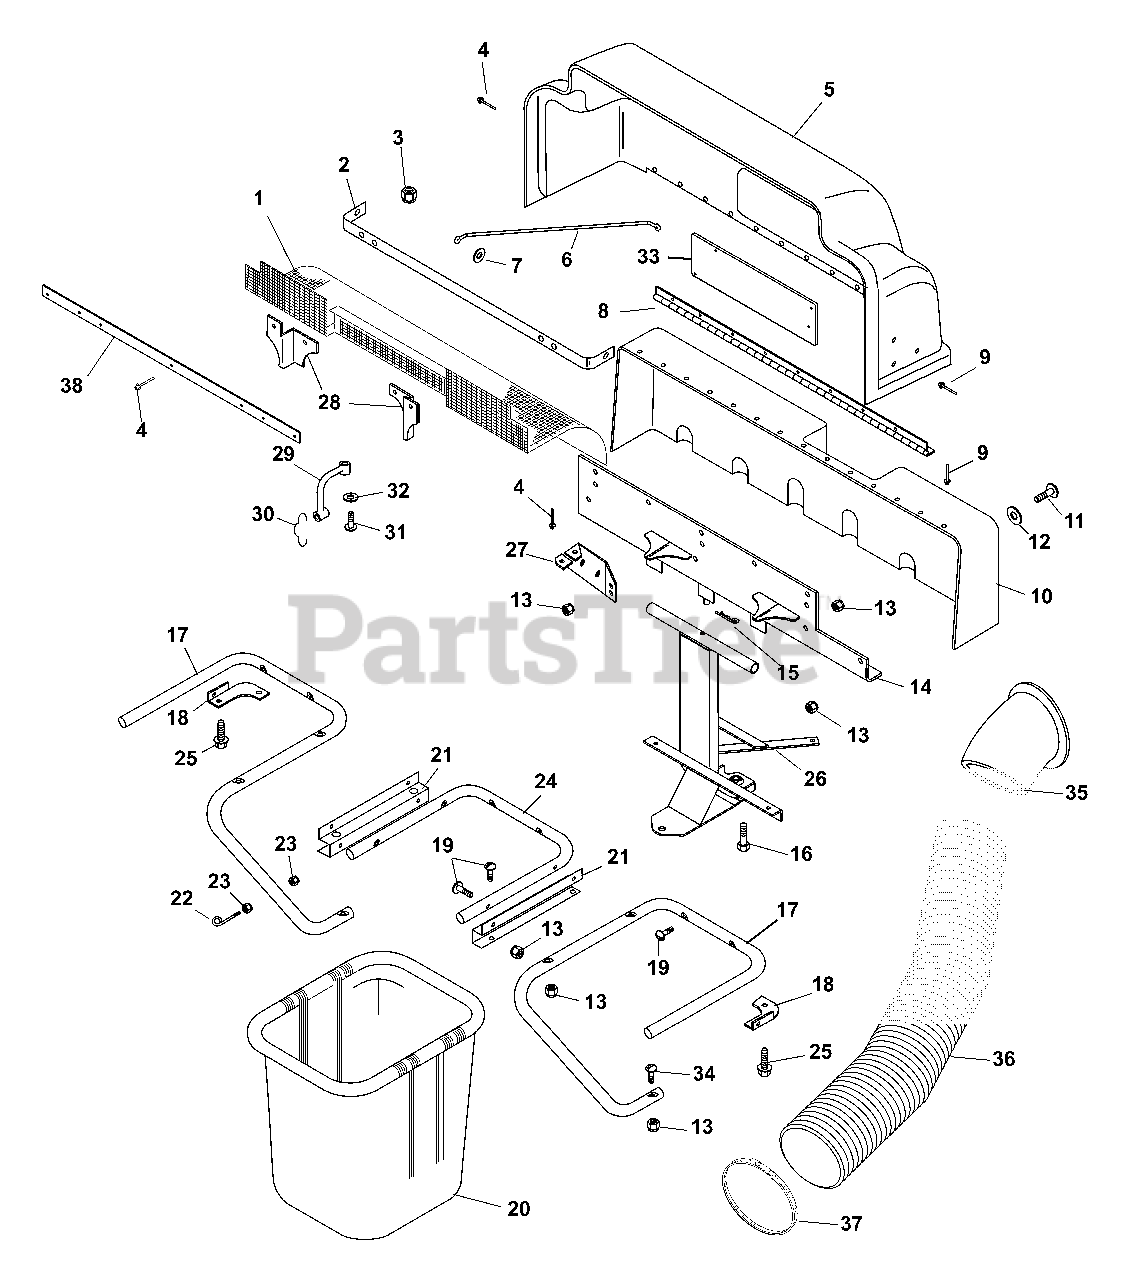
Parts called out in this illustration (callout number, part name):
2	Screen Mounting Bracket
3	Nut-Locking-Top 10-24
4	Rivet-Pop .187 x .527
5	Hinged Cover w/Decals
7	Washer-Flat-Steel .194 x .492 x .047
9	Rivet-Pop .187 x .402
10	Stationary Cover
11	Bolt-Hex .31-18 x 1.00 Grade 2
12	Washer-Flat-Steel .344 x .063
13	Nut- Locking-Nylon .312-18 Grade 2
14	Mounting Bracket
15	Pin-Hair Internal .08 x .38 x 1.42
16	Bolt-Hex .50-13 x 1.25 Grade 2
17	Right Tube
17	Left Tube
18	Right Hand Corner Bracket
18	Left Hand Corner Bracket
19	Screw-Machine .31-18 x 1.50
20	Grass Bagger Bucket
21	Tube Bracket
23	Nut-Locking-Center .250-20
24	Center Tube
25	Screw-Tapping .312-18 x .50
26	Bagger Frame
28	Baffle Left Hand
28	Baffle Right Hand
29	Battery Strap
31	Screw-Machine 10-24 x 1.00
32	Washer-Flat Steel
34	Screw, .312-18 x 2.00
35	Bagger Boot, Upper
36	Hose 7 x 35
37	Clamp, Hose-Worm 2.13/8.62 x .56
38	Guard, Screen
